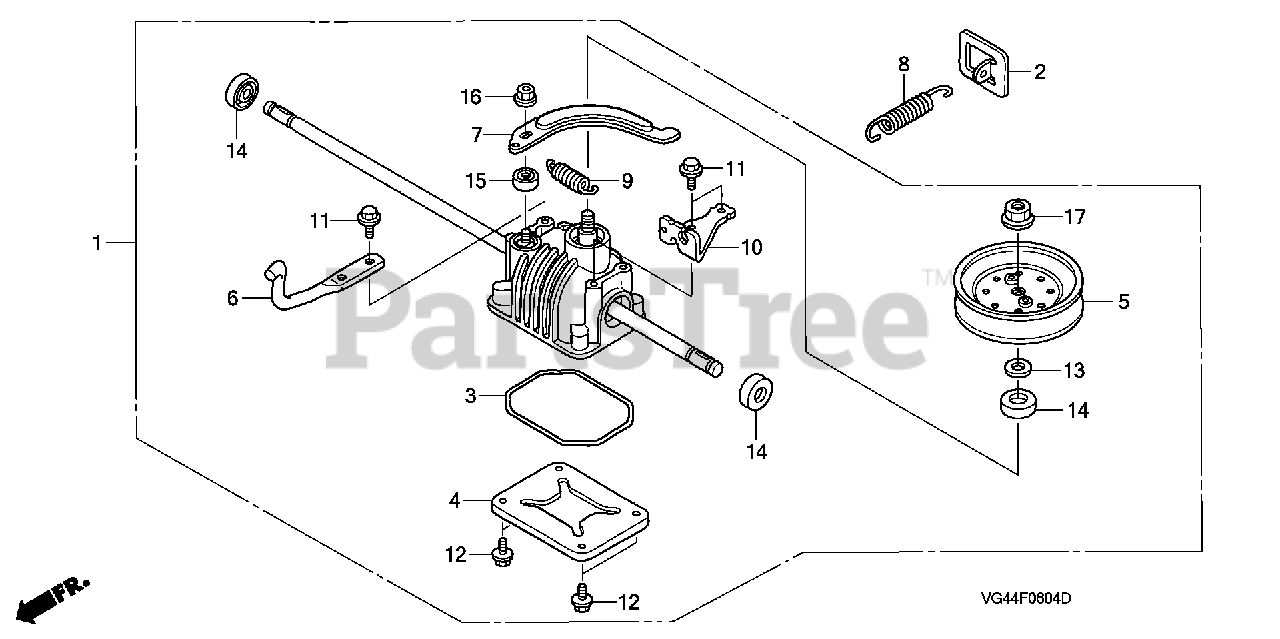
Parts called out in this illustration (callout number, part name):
1	TRANSMISSION KIT
2	PLATE, TENSION SPRING
3	O-RING, CASE
4	COVER, REDUCTION
5	PULLEY, DRIVEN
6	ARM, TENSIONER
7	ARM, CONTROL
8	SPRING, WHEEL TENSION
9	SPRING, RETURN
10	HOLDER, WIRE
11	BOLT, FLANGE (6X14) (CT200)
12	BOLT, FLANGE (6X12) (CT200)
13	WASHER (10X24)
14	OIL SEAL (12.7X28.6X6.4)
15	OIL SEAL (10X19X7)
16	NUT, FLANGE (6MM)
17	NUT, FLANGE (10MM)
